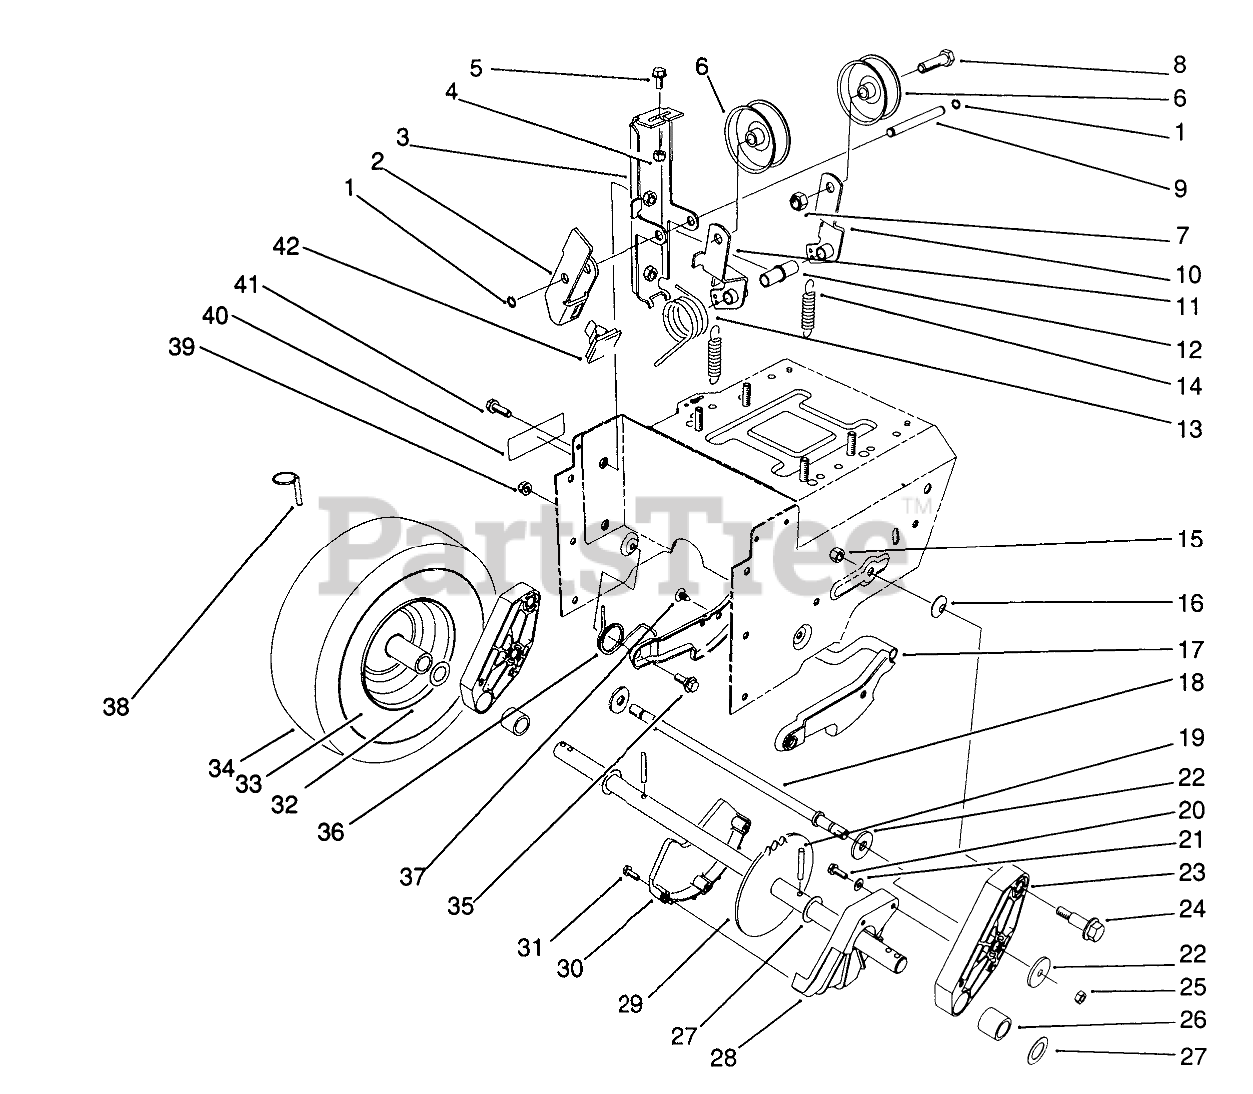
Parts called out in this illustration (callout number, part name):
1	RING-RETAINING
2	ARM-BRAKE
3	IDLER ARM BRACKET ASM
4	NUT-LOCK, NI
5	SCREW-HHF
6	PULLEY-IDLER
7	NUT-LOCK, NI
8	SCREW-HH
9	PIN-IDLER
10	ARM-IDLER, TRACTION
11	ARM-IDLER, IMPELLER
12	BUSHING-IDLER
13	TORSION SPRING
14	SPRING-EXTENSION
15	NUT-LOCK, NI
16	WASHER-SPRING
17	Latch-Arm
18	ROD-LATCH
19	PIN-ROLL, SLOTTED
20	SCREW-HWH
21	WASHER-FLAT
22	WASHER-SUPPORT
23	Pivot Arm Assembly (Incl. Ref. #26)
24	BOLT-SHOULDER
25	NUT-LOCK, NI
26	BUSHING-AXLE
27	WASHER-THRUST
28	GUARD-CHAIN, LH
30	GUARD-CHAIN, RH
31	Screw
32	RIM-WHEEL
33	INNER TUBE
35	SCREW-SHOULDER
36	SPRING-LATCH, TORSION
37	FASTENER-PANEL
38	PIN-LYNCH
39	NUT-LOCK, NI
40	DECAL-WARNING
41	SCREW-HHF
42	PAD-BRAKE
